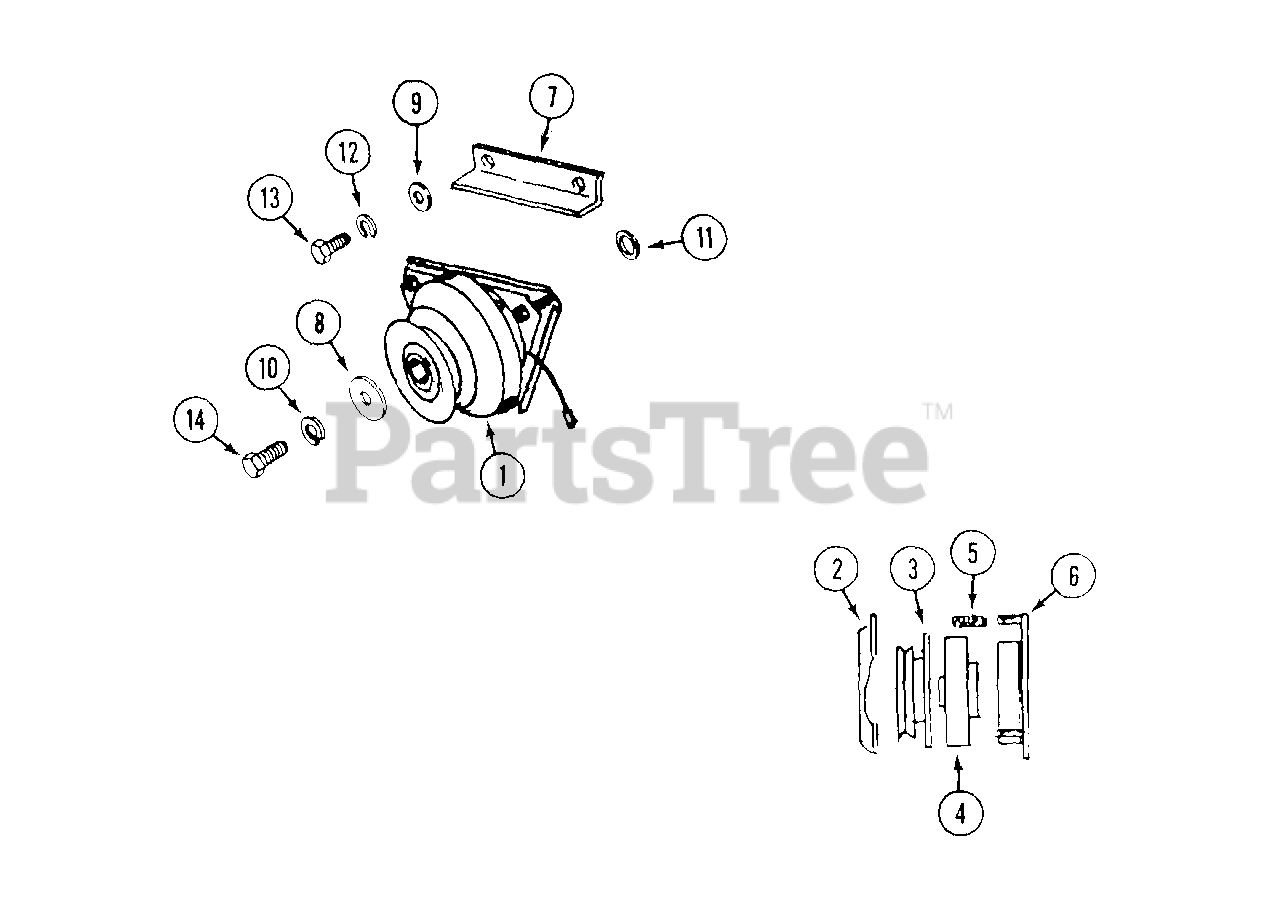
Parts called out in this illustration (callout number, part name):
1	CLUTCH ASSEMBLY
2	BRAKE - clutch
3	ARMATURE - clutch
4	ROTOR - clutch
5	KIT - spring and nut (3 each)
6	COIL - clutch
7	BRACKET - clutch stop
8	WASHER - retaining
9	WASHER - .438" x 1"
10	LOCKWASHER - 3/8"
11	WASHER - 1-1/8"
12	LOCKWASHER - 7/16"
13	BOLT - 7/16" - 14 x 3/4"
14	BOLT - 3/8" - 24 x 1-1/2"
